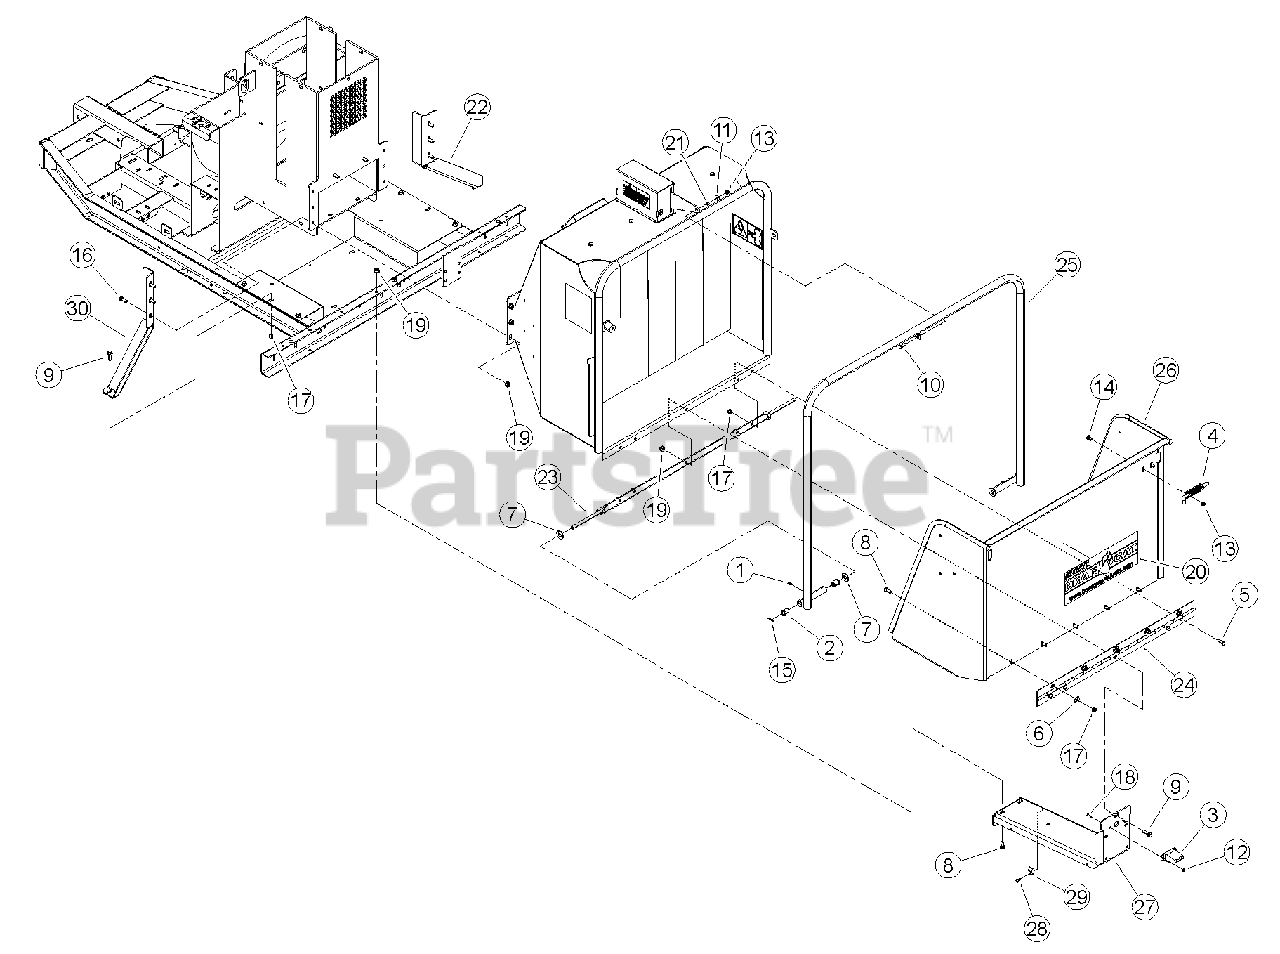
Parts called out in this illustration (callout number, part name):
1	FITTING, 1/4 SELF-TAP GREASE
2	BUSHING, 1/2 X 1 FLANGE LUBE
3	LIGHT, LICENSE PLATE
4	LATCH, RH HINGE
5	BOLT, 3/8 X 1 HEX HD GR5 ZP
6	WASHER, 3/8" FLAT ZP
7	WASHER, 1/2" FLAT ZP
8	BOLT, 3/8 X 1" GR5 CRG NC ZP
9	BOLT, 3/8 X 1-1/4 FLANGE NC
10	BOLT, 5/16 X 1" GR5 HHCS NC ZP
11	WASHER, 5/16" FLAT ZP
12	NUT, 8-32 NYLOCK
13	NUT, 5/16" NE NYLOCK ZP
14	BOLT, 5/16 X 3/4 GR5 CRG NC ZP
15	PIN, 1/8 X 1.00 ZP COTTER
16	BOLT, 3/8 X 1-1/4" GR5 CRG NC ZP
17	NUT, 3/8" NE NYLOCK ZP
18	SCREW, MCH 10-24 X 3/4" PAN HD PH ZP
19	NUT, 3/8-16 NYLOCK FLANGE
20	DECAL, BEARCAT WEB
21	SPACER, IDLER PIVOT
22	BRACKET, CHUTE SUPPORT RH
23	WELDMENT, CONTROL PIVOT
24	HINGE, EXTENSION TRAY
25	WELDMENT, CONTROL ARM
26	WELDMENT, EXTENSION TRAY
27	ASSEMBLY, CHUTE/SPARE SUPPORT 6 IN SERVICE PART
28	RIVET, AL BLIND 1/4 X 3/4 DOME HEAD
29	CLAMP, CABLE MOUNT
30	WELD, PLATE LH SUPPORT
